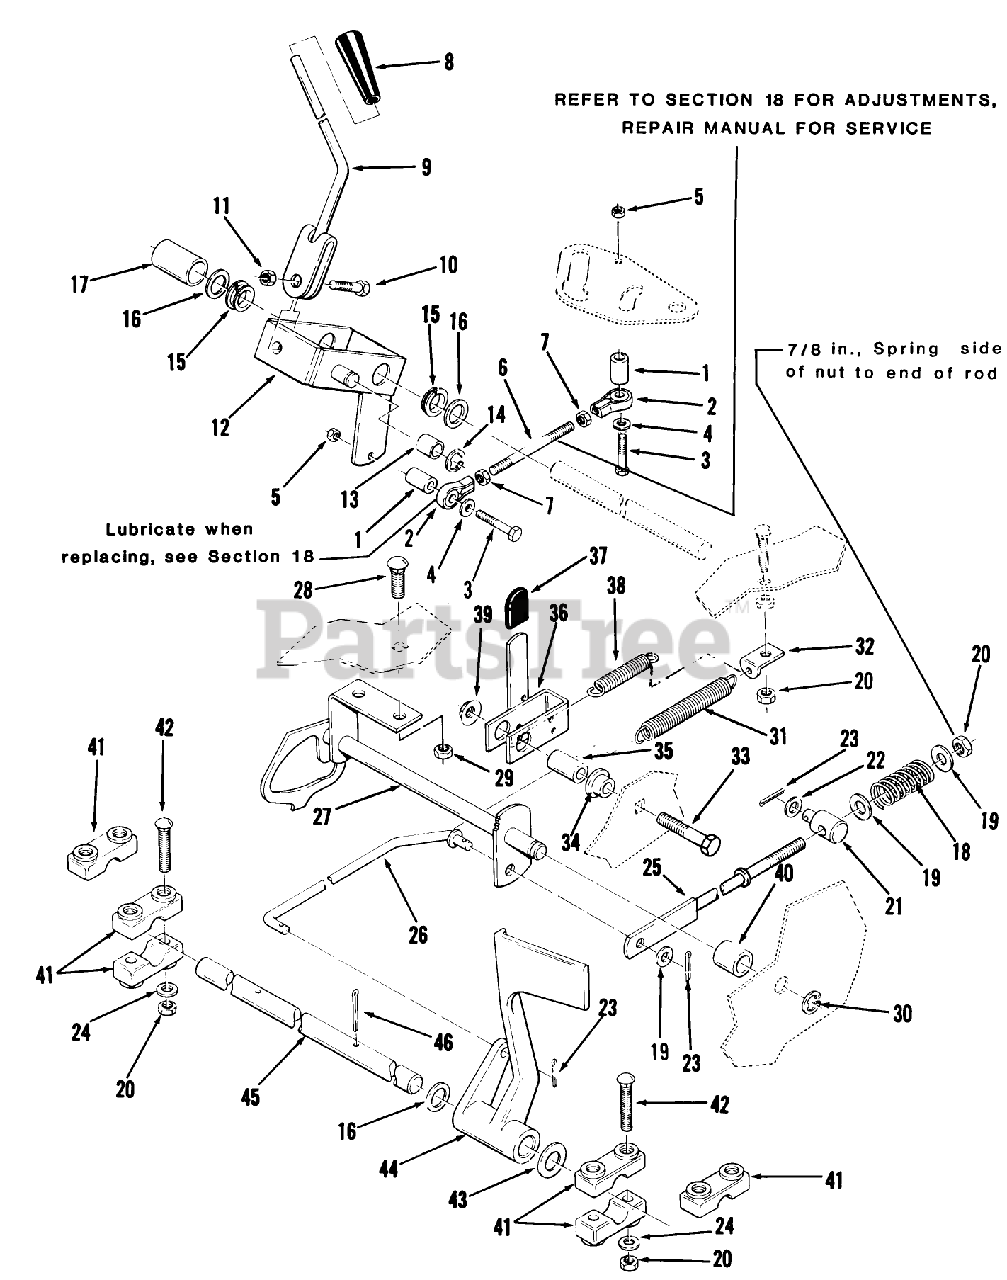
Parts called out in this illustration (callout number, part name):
1	BEARING CAM ROLLER
2	ASSY ROD END
8	KNOB
13	BEARING-CAM RETURN
21	TRUNNION-LIFT
24	WASHER 5/16 SAE
32	CLIP - SPRING
34	SPACER
35	SPACER
37	GRIP
43	Special Washer
44	PEDAL CLUTCH *R
